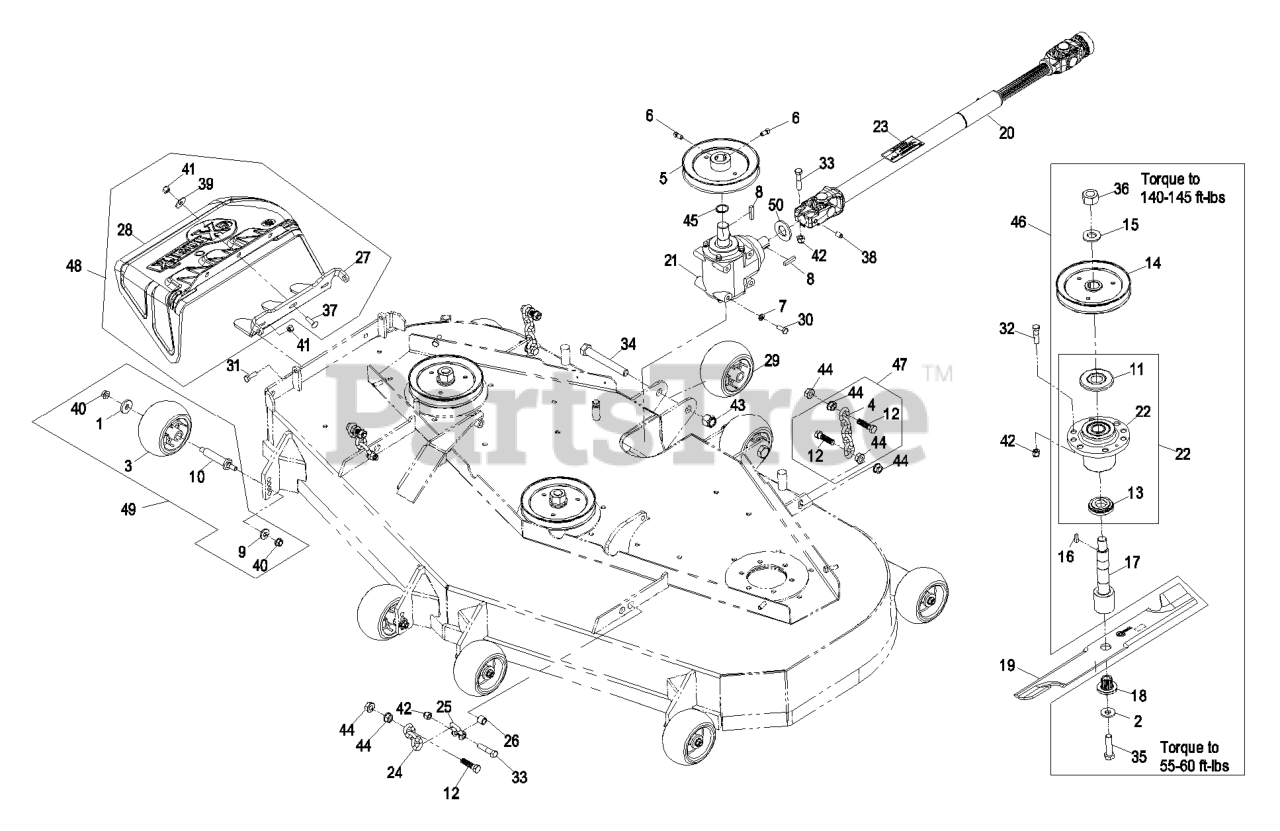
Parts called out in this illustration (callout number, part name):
2	WASHER-SPRING
3	ROLLER-SCALP, ANTI
4	CHAIN-LIFT, DECK
5	SHEAVE-SPLIT
6	SCREW-SET
7	WASHER-LOCK
8	KEY-SQUARE
9	WASHER-BELLEVILLE
11	GUARD-BEARING, TOP
12	SCREW-HH
13	SPACER-GUARD, BOTTOM
14	SHEAVE,BLADE DRIVE 6.30
17	KIT, SPLINED SPINDLE 103-
18	BUSHING,SPLINED
21	GEARBOX,90 DEGREES
22	KIT, CUTTER HOUSING
23	DECAL-DRIVELINE
24	CHAIN-DECKLIFT
25	SHACKLE,FRONT CHAIN
26	BUSHING,SHACKLE
27	BRACKET,DISCHARGE CHUTE
28	CHUTE,DISCHARGE
29	ROLLER, FULL HUB
30	SCREW-HH
31	SCREW-HH
32	SCREW-HH
33	SCREW-HH
34	SCREW-HH
35	SCREW-HH
36	NUT-HH
37	SCREW-CARR
38	SCREW-SET
39	WASHER-FLAT
40	NUT-HHF, WHIZ
41	NUT-LOCK, NI
42	NUT-LOCK, NI
43	NUT-LOCK, NI
45	RING-RETAINING
46	ASM, CUTTER HSG COMPLETE
47	DECK CHAIN ASM
50	WASHER,SPECIAL
